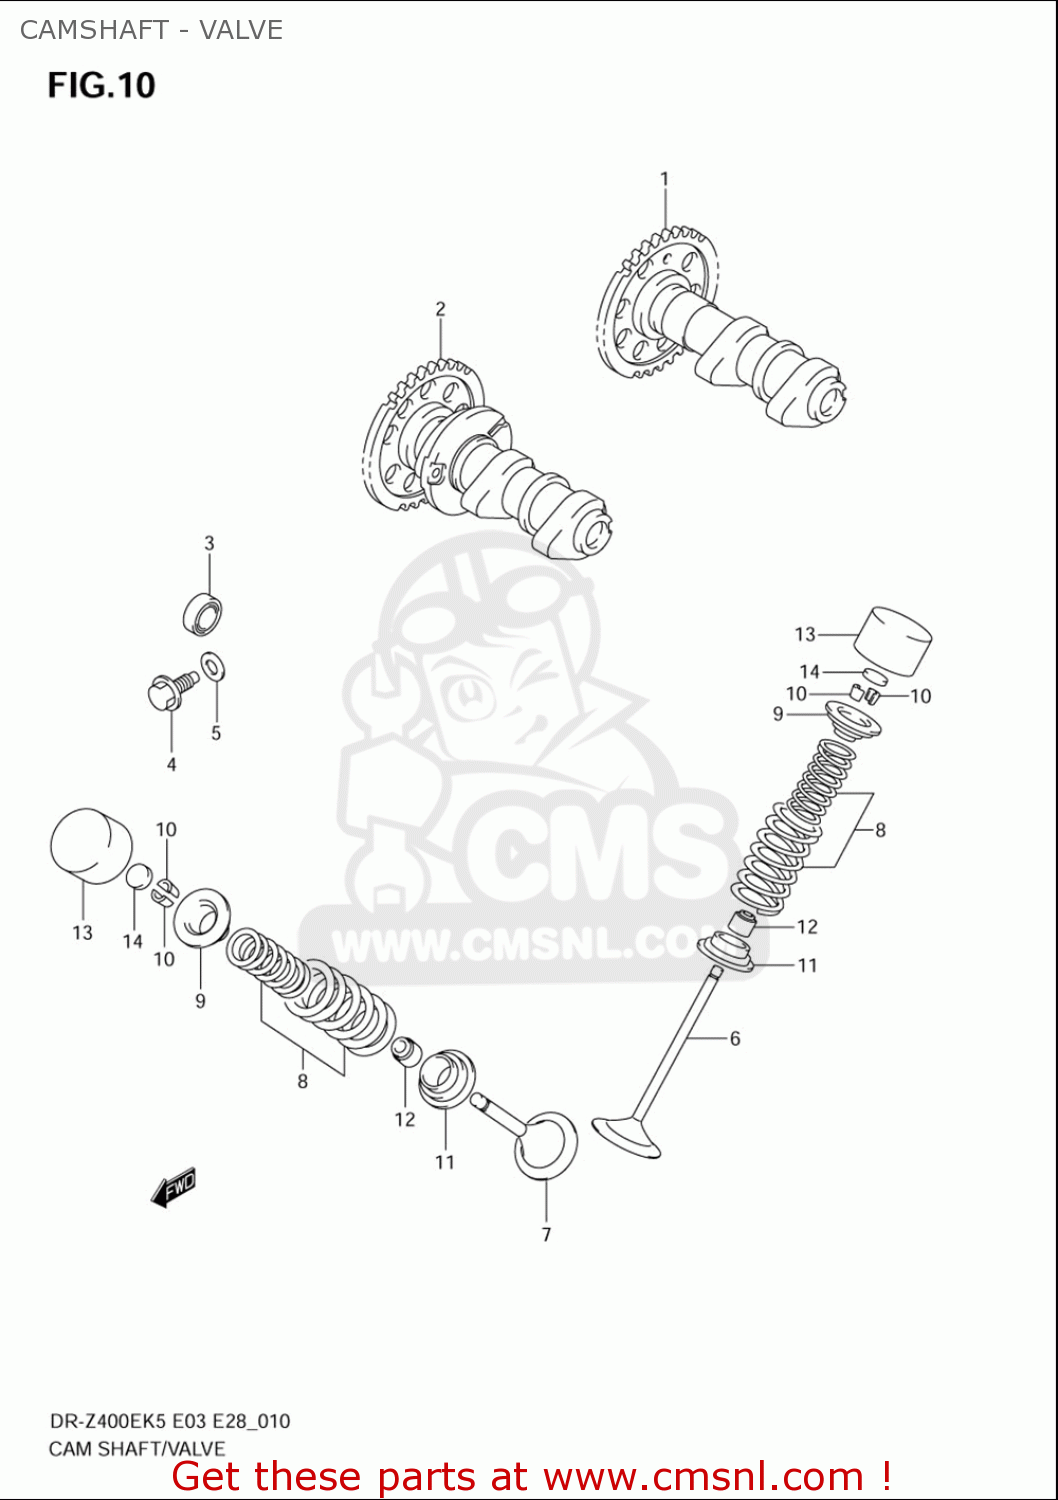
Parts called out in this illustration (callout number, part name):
1	CAMSHAFT,INTAKE
2	CAMSHAFT COMP,EXHAUST
3	SEAL,OIL(10X17X6)
4	BOLT 6X12
5	GASKET(5.8X13X1.2) (NAS)
6	VALVE,INTAKE
7	VALVE,EXHAUST
8	SPRING SET,VALVE
9	RETAINER,VALVE SPRING
10	COTTER VALVE
11	SEAT,VALVE SPRING
12	SEAL,OIL(5X10X9.7)
13	TAPPET
14	SHIM,TAPPET(T:2.3)
15	SHIM SET,TAPPET
16	CASE,TAPPET SHIM
